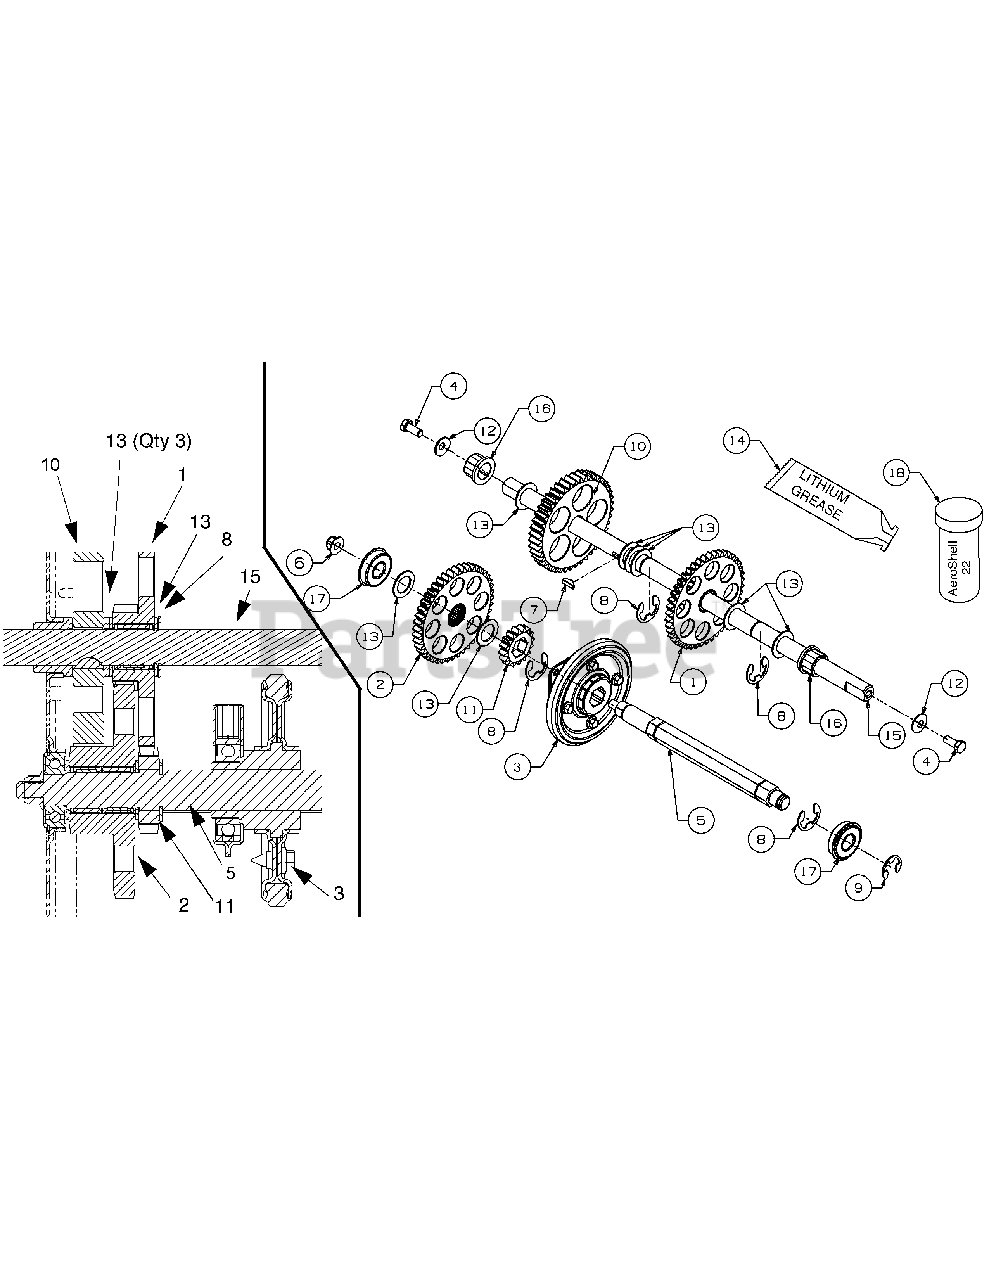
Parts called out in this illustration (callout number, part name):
1	GEAR ASSEMBLY: 16(Narrow)/44T
2	GEAR ASSEMBLY: 16 (Wide)/44T
3	WHEEL ASM: FRICTION: 4.9" OD
4	SCREW: LOCK: 5/16"-24 x .75: GR5
5	HEX SHAFT: DRIVE
6	NUT: FLANGELOCK: 3/8"-16: GRF
7	KEY: HI-PRO- 3/16" X 5/8"
8	E-RING: RETAINER: .875 DIA.
9	E-RING: RETAINER: .750 DIA.
10	GEAR: 44T
11	GEAR: PINION: 16T: .8125 HEX
12	WASHER: BELL: .340 x .872 x .060
13	WASHER: FLAT: .793x 1.24x .06 HT
14	GREASE: LITHIUM: WHITE
15	AXLE: .75 DIA. x 20" LG
16	BEARING: HEX FLANGE x .75 ID
17	BEARING: BALL: 17 x 40 x 12
18	GREASE: AEROSHELL 22
